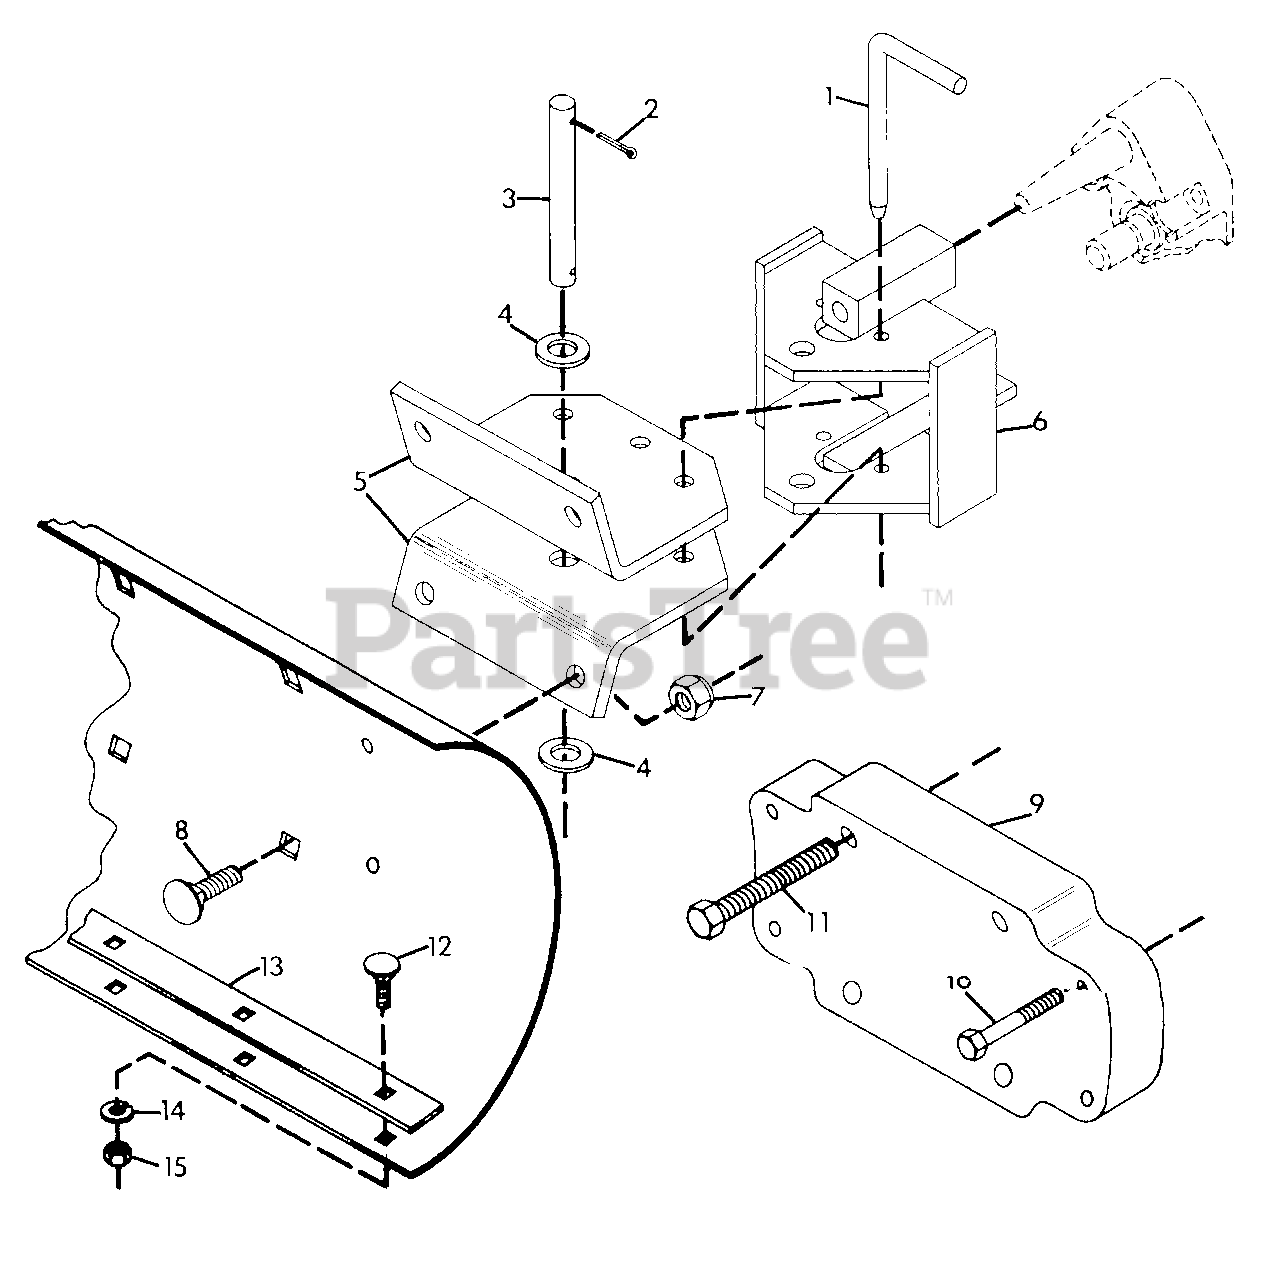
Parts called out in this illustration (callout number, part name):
12	BOLT, 5/16-18X1.00 RD HD SQ NK
13	STRIP, WEARING
14	WASHER, LOCK 5/16 INTERNAL TOOTH
15	NUT, HEX 5/16-18
